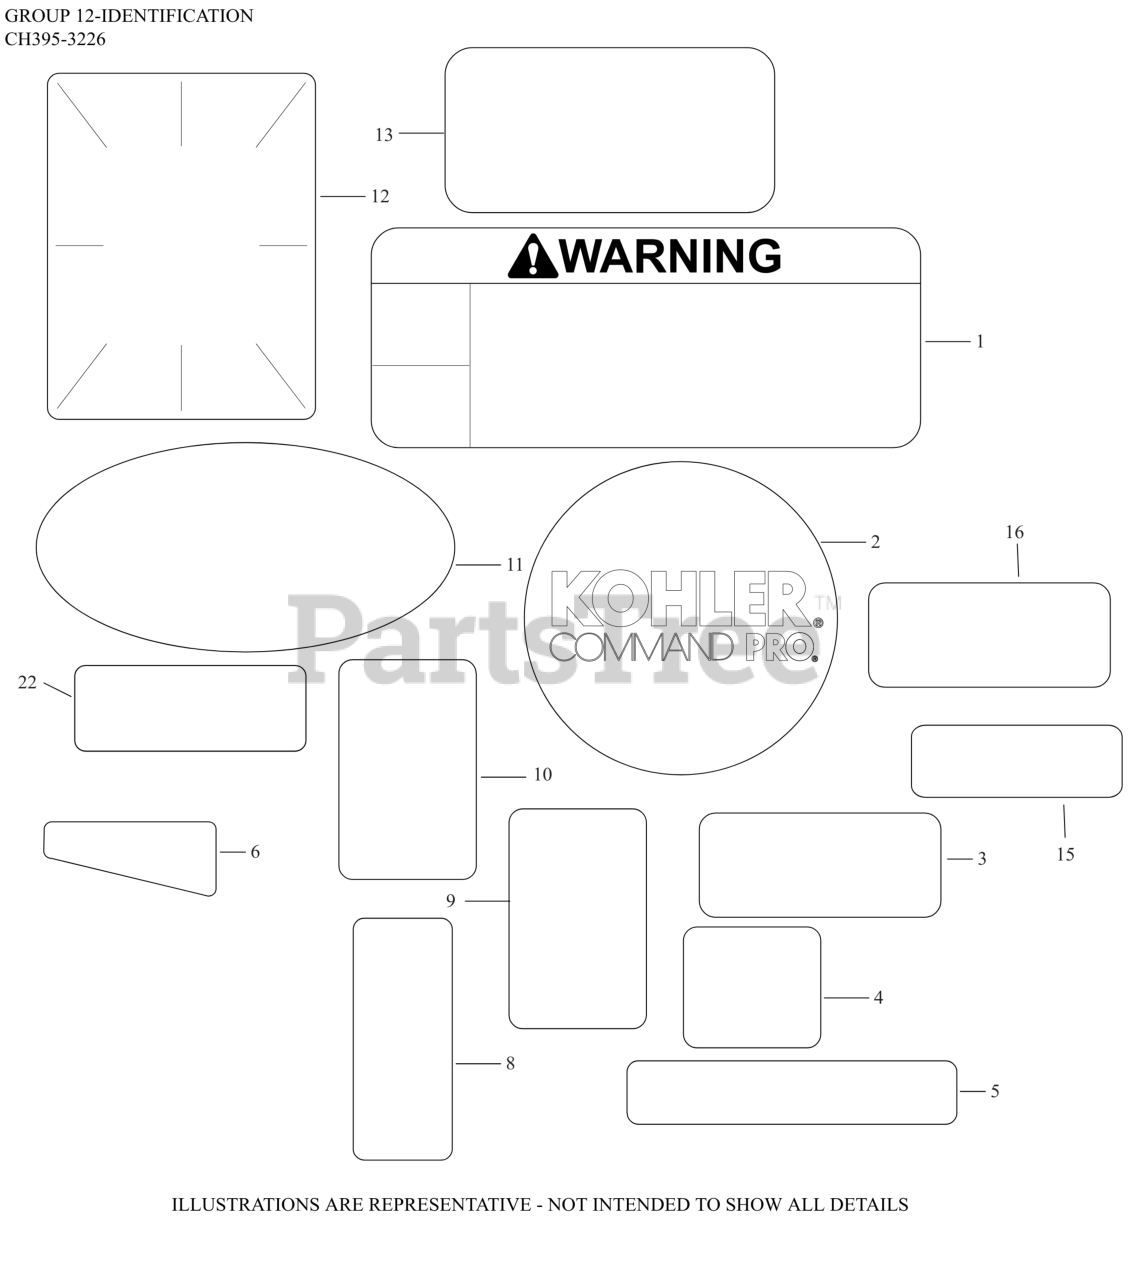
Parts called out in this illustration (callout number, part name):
1	DECAL, WARNING
2	LABEL, RECOIL 75MM
3	LABEL, CANADIAN COMPLIANCE
4	DECAL, BASE ARROW
5	DECAL, THROTTLE
6	DECAL, 9.5 HP/277cc/CH395
8	DECAL, FUEL/CHOKE - ON/OFF
9	DECAL, SUN
10	DECAL, SNOW FLAKE
11	DECAL, QUAD CLEAN SILVER
12	LABEL, CLEAR LAMINATION
13	LABEL, MAINTENANCE (CKY)
15	DECAL, ENGINE AND FUEL SHUT OFF
16	DECAL, ETHANOL WARNING
